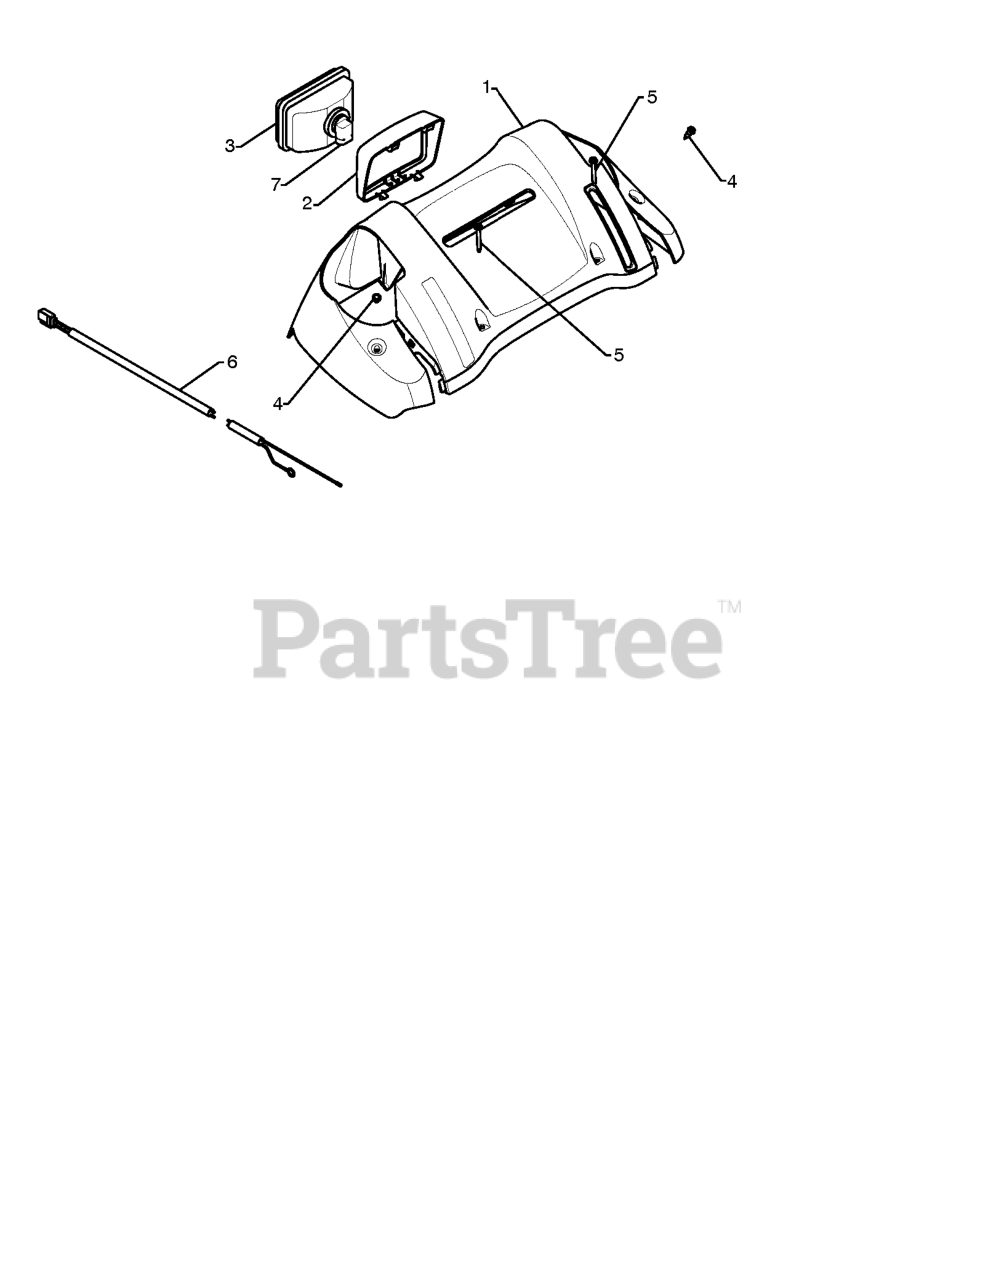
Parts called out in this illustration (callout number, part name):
1	PANEL.CONSOLE.FLOOD.LIGHT.GREY
2	BEZEL.HEADLIGHT
3	HEADLIGHT.HALOGEN.SNOW
4	SCREW, HEX HEAD, TAPPING
5	SCREW, HEX HD TAPPING #10-24 1
6	HARNESS.WIRE.HALOGEN
7	BULB.HEADLIGHT.HALOGEN.
